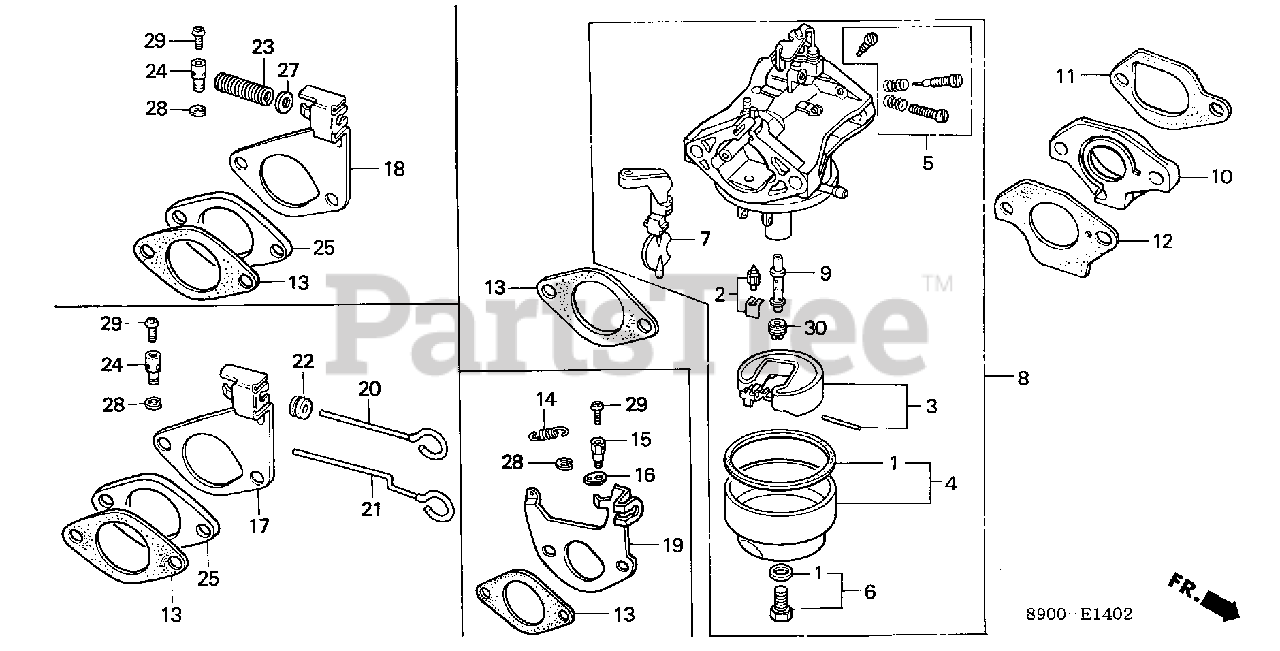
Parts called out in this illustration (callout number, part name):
1	GASKET SET (CARBURETOR NO.)
2	VALVE SET, FLOAT
2	VALVE SET, FLOAT (CARBURETOR NO.)
3	FLOAT SET (CARBURETOR NO.)
4	CHAMBER SET, FLOAT (CARBURETOR NO.)
4	CHAMBER SET, FLOAT (CARBURETOR NO.) (NOT AVAILABLE)
5	SCREW SET A (CARBURETOR NO.)
6	SCREW SET (CARBURETOR NO.)
6	SCREW SET
7	CHOKE SET (CARBURETOR NO.)
8	CARBURETOR ASSY. (BB35C G)
9	NOZZLE, MAIN (CARBURETOR NO.) (NOT AVAILABLE)
10	INSULATOR, CARBURETOR
11	GASKET, INSULATOR
12	GASKET, CARBURETOR
13	GASKET, AIR CLEANER
17	STAY, CHOKE CONTROL (NOT AVAILABLE)
20	ROD, CHOKE CONTROL (NOT AVAILABLE)
22	GROMMET, CHOKE ROD
24	HOLDER, CABLE
25	SPACER, AIR CLEANER (NOT AVAILABLE)
28	CIRCLIP (5MM)
29	SCREW, PAN (4X8)
30	JET, MAIN (#88) (CARBURETOR NO.)
30	JET, MAIN (#90) (CARBURETOR NO.)
30	JET, MAIN (#92) (CARBURETOR NO.)
30	JET, MAIN (#95) (CARBURETOR NO.)
30	JET, MAIN (#98) (CARBURETOR NO.)
30	JET, MAIN (#100) (CARBURETOR NO.)
30	JET, MAIN (#102) (CARBURETOR NO.)
